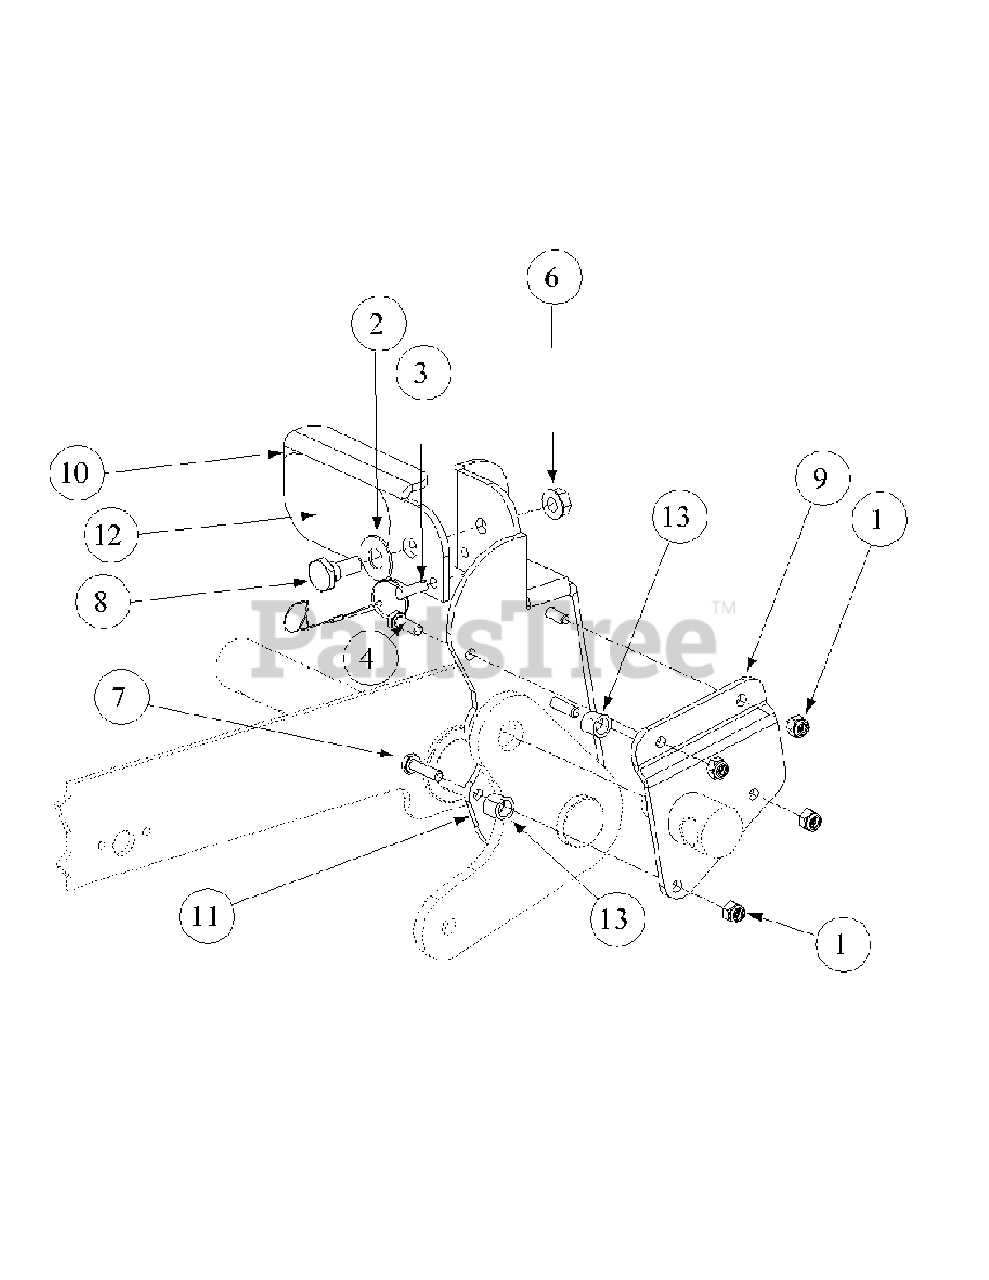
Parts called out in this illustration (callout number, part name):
1	Lock Nut, Nylon Insert, 1/4-20
2	Washer, 1/2 x 1 Shim
3	Detent Pin w/Lanyard, 1/4"
4	Hex Cap Screw, 1/4-20, .75
6	Hex Nut, Flange Lock 3/8-16
7	Hex Cap Screw, 1/4-20, 1.00
8	Shoulder Screw, .50x.27 Lg., 3/8-16
9	Foot Lift Backup Pedal
10	Deck Foot Pedal Lift
11	Deck Foot Pedal Lift Holder
12	Deck Foot Lift Pad
13	Turnbuckle Sleeve
